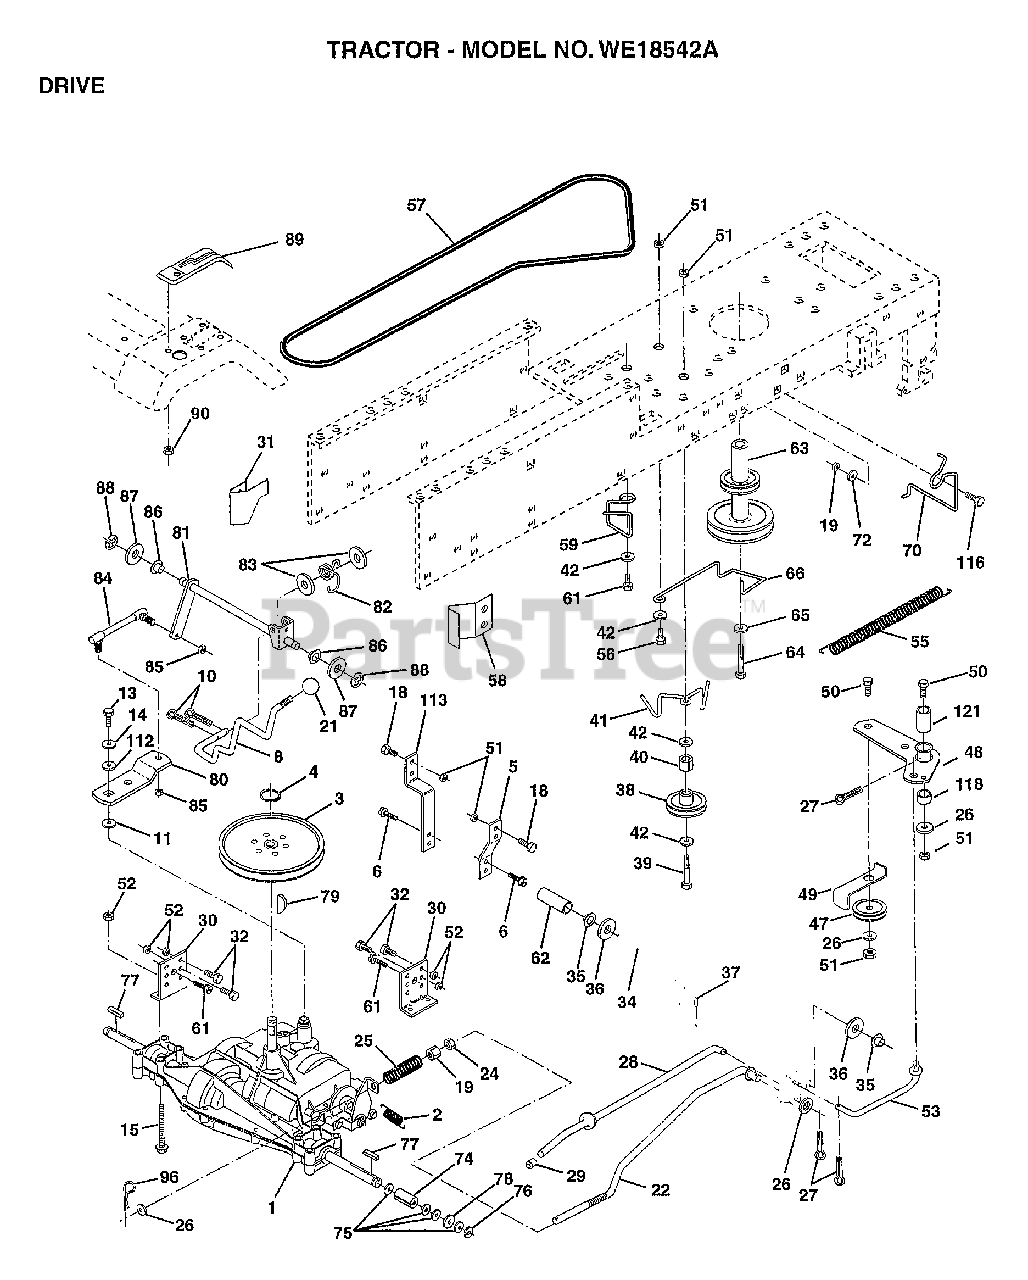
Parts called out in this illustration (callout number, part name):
1	TRANSAXLE PEERLESS
2	SPRING.BRAKE.RETU
3	PULLEY TRANS
5	STRAP TORQUE
6	SCREW
8	ROD SHIFT FEND LT
10	PIN COTTER 1/8
11	WASH-SHFT PLT LT
13	BOLT.1/4-28.W/PAT
14	LOCKWASHER
15	BOLT.HX.FLG.5/16
18	BOLT
19	NUT
21	KNOB T (1/2-HOLE)
22	BRAKE ROD
24	NUT
25	SPRING ROD LT
26	WASHER
27	COTTER PIN
28	ROD.BRAKE.PARK.LT
29	PLUNGER CAP T
30	TRANSAXLE MTG BKT
31	"KEEPER,BELT LH T"
32	BOLT
34	SHAFT ASM-PEDAL F
35	NYLON BEARING
36	WASHER LT
38	PULLEY.IDLER.FLAT
39	BOLT
40	SPACER T
42	WASHER
48	BELLCRANK ASM
49	RETAIN BELT
53	"LINK, CLUTCH T"
55	"SPRING, RETURN LT"
58	"KEEPER,BELT RH T"
59	KEEPER BELT CNTSP
61	SCREW
62	PEDAL COVER T
63	PULLEY.ENGINE
64	BOLT
65	LOCKWASHER
66	KEEPER-BELT
70	KEEPER BELT ENG
72	WASHER
74	SPACER AXLE
75	WASHER
76	E-RING LT
77	SQUARE KEY
78	WASHER
80	"ARM.SHIFT.20""TIRE"
81	SHAFT.CROS.P930.
82	"SPRING,TORSION"
83	WASHER
84	"ROD.TIE.20""P930LT"
85	NUT.CNT.LOCK.1/4
86	BUSHING
87	WASHER D
88	KLIP RING
90	NUT
96	RETAINER M
112	WASHER LT
113	"STRAP,TORQUE"
116	BOLT RDHD 3/8-16
118	SPACER-BELLCRANK
121	NYLINER-CLUTCHING
